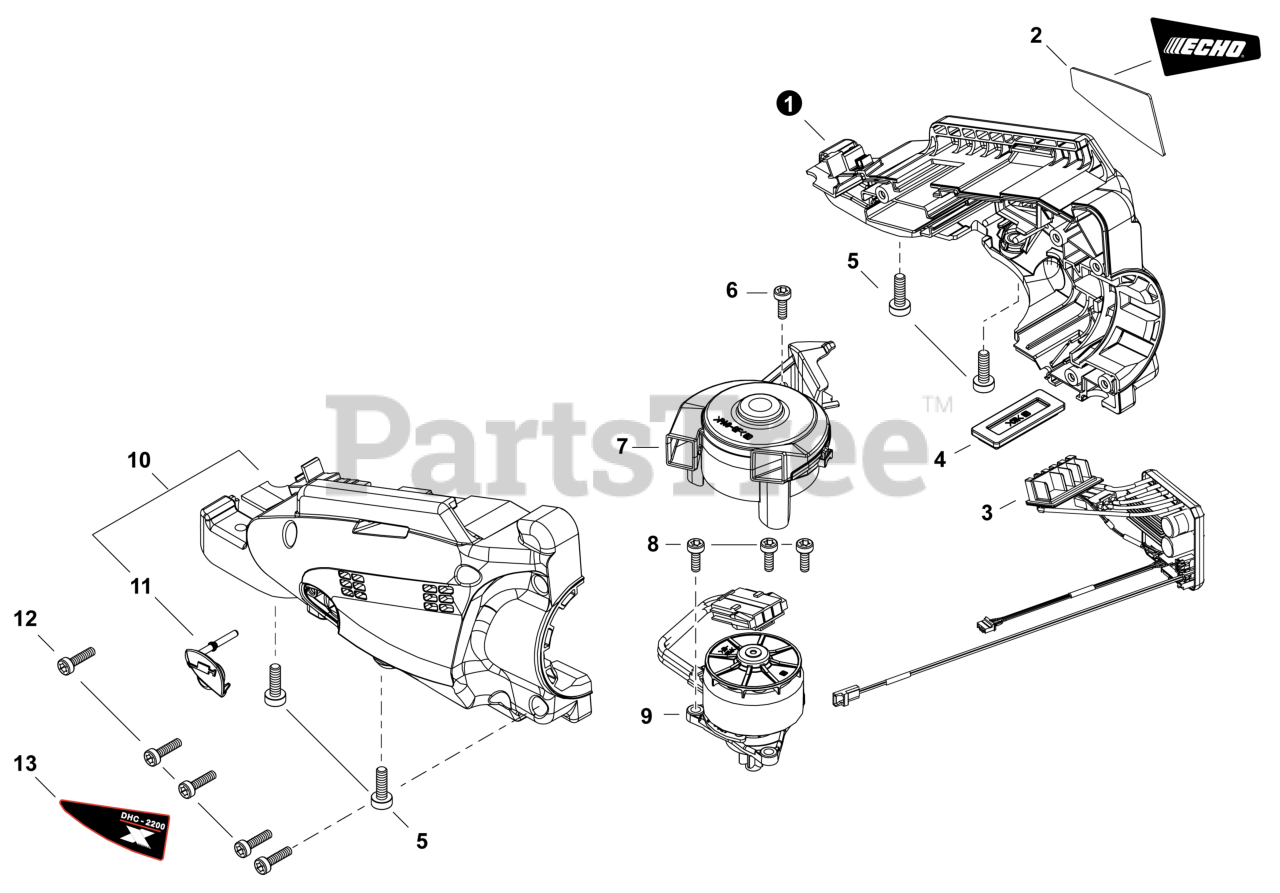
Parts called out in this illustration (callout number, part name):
1	COVER, MOTOR - RIGHT
2	LABEL - ECHO
3	CONTROL BOARD ASSY
4	CUSHION
5	BOLT, TORX 5x16
6	BOLT, TORX 4x12
7	CASE ASSY, FAN
8	BOLT, TORX 4x12
9	MOTOR ASSY
10	COVER ASSY, MOTOR - LEFT
11	CAP, CUP GREASE
12	BOLT, TORX 4x16
13	LABEL - MODEL DHC-2200
